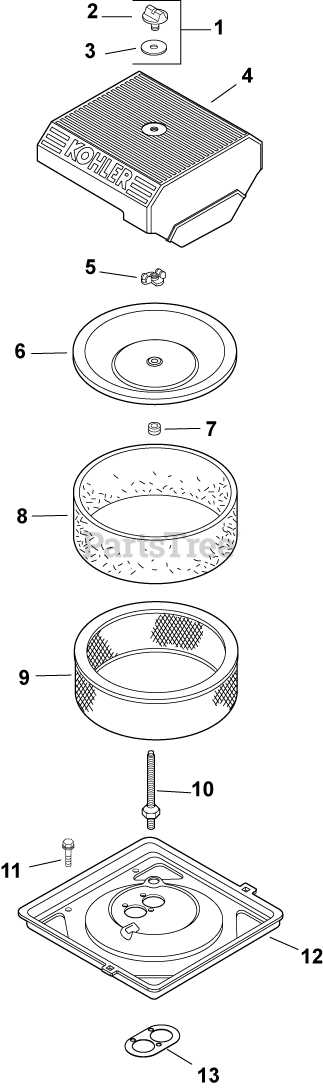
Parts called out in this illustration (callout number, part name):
1	KIT, KNOB W/SEAL
2	KNOB, COVER
4	COVER, AIR CLEANER
5	NUT, WING
6	COVER, INNER AIR CLEANER
7	SEAL, BREATHER
8	PRE-CLEANER (HIGH)
9	ELEMENT, AIR FILTER (HIGH) - Also available Retail Packaged 24 883 03-S1 Air Filter Kit
11	SCREW, FLG M6X1.0X12
12	BASE, AIR CLEANER-USE 24 094 83-S
13	GASKET, AIR CLEANER BASE
